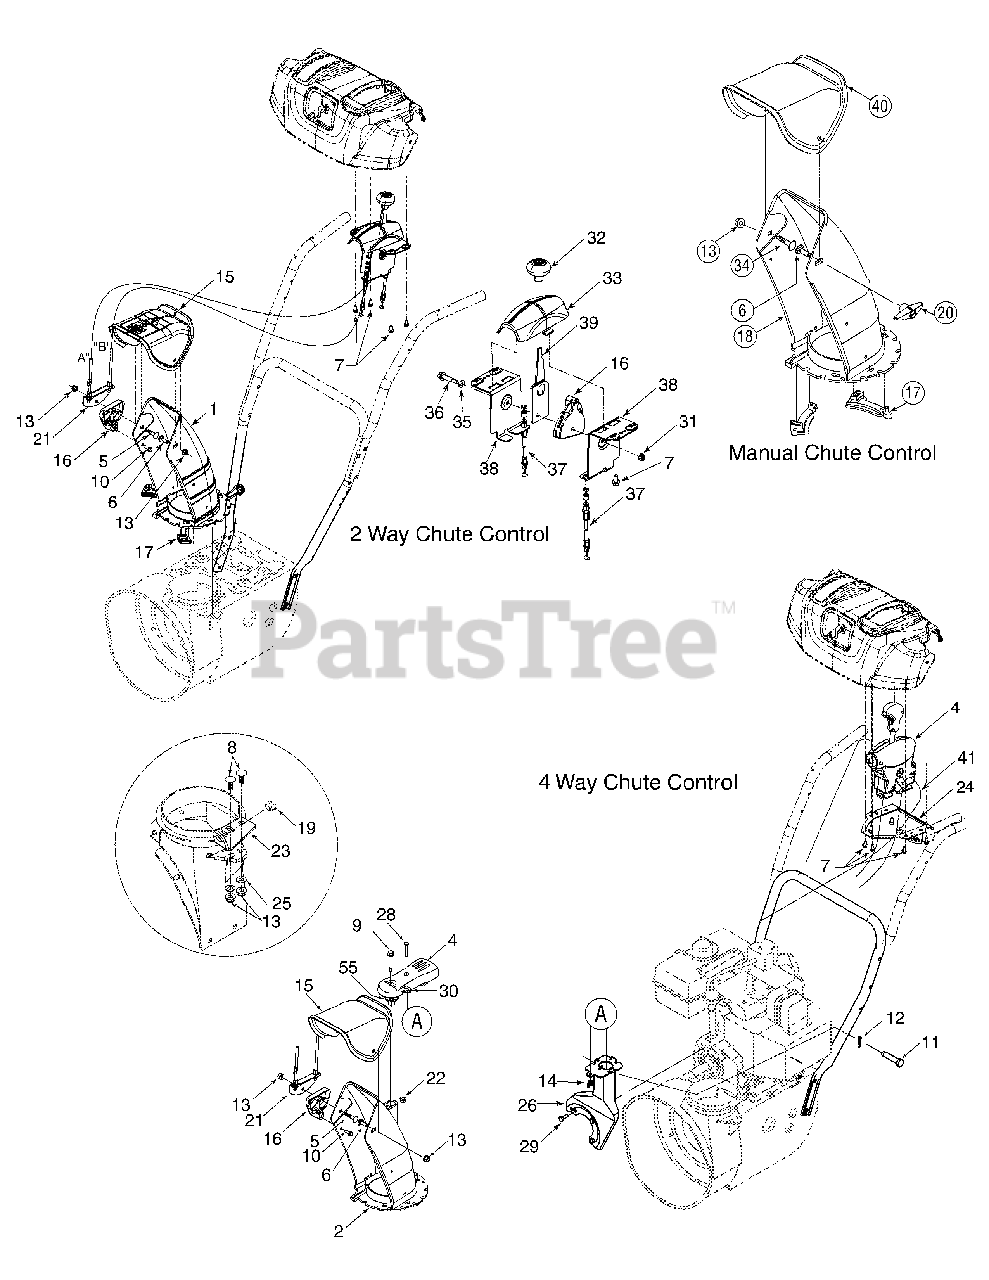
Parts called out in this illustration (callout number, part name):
1	Lower Chute
2	Lower Chute
3	2 Way Chute Control Assembly
4	4 Way Chute Control Assembly Service Kit
5	Carriage Bolt 5/16-18 x 1.50 Gr. 2
6	Carriage Screw 5/16-18 x 1.0
7	Hi-Lo Screw 1/4-15 x .5
8	Carriage Bolt 5/16-18 x 1.00'' Lg
9	Shoulder Screw .312 x 1.7:1/4-20
10	Hex Tapp Screw 1/4 x .75'' Lg
11	Clevis Pin 3/8 x 1.87
12	Bow tie Cotter Pin
13	Flange Locknut 5/16-18 Gr. F Nylon
14	Wing Nut 1/4-20
15	Upper Chute w/Label, Remote
16	Cable Guide
17	Chute Flange Keeper
18	Lower Chute
19	Plastic Bushing .380 ID
20	Handle Knob Assembly
22	Hex L-Flanged Nut 1/4-20 Gr. F Nylon
25	Flat Washer .349 ID x .879 OD x .063
26	Support Bracket
27	Hi-Lo Screw 1/4-15 x .50
28	Hex Hd Cap Screw 1/4-20 x 1.5 Gr. 5
29	Hex Hd Cap Screw 5/16-24 x .75
30	Flat Washer .25 ID x .63 OD x .0515
31	Flange Locknut 1/4-20 Gr F Nylon
33	Control Cover - 2 Way
34	Carriage Bolt 5/16-18 x .75
35	Spring Washer .390 x .625 x .012
36	Flange Shoulder Spacer .310 x .995 x 1/4-20
37	Cable - 2 Way
40	Upper Chute
